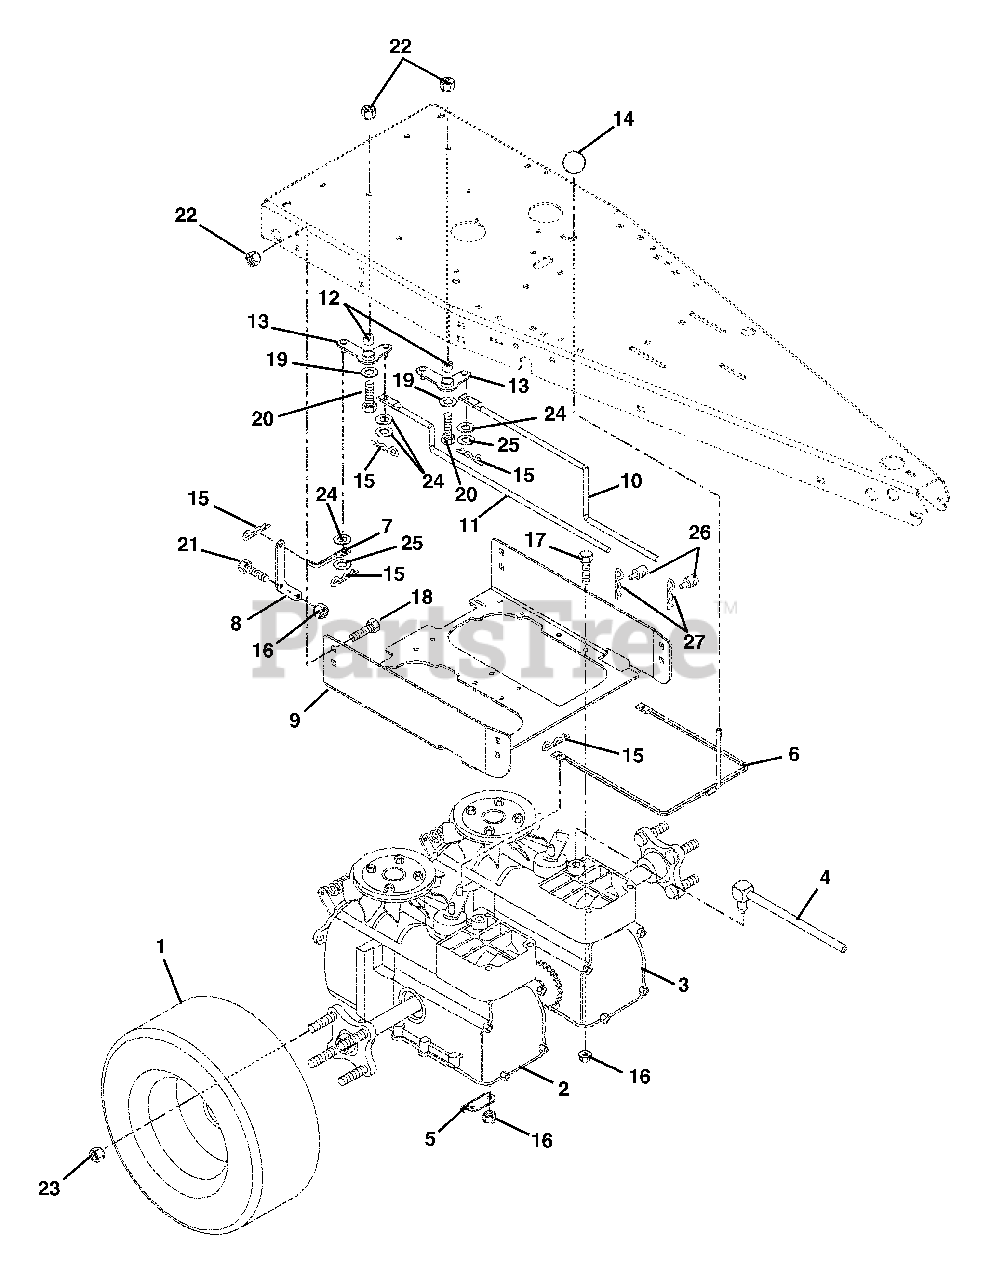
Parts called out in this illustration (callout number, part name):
1	T/WHL ASM 18X6.50-8 2 PLY
2	TRANSAXLE, HYDRO-GEAR
3	TRANSAXLE, HYDRO-GEAR
4	IZT, BREATHER ASSEMBLY
5	BRACKET-AXLE SUPPORT
6	DUMP ROD WLDM'T
7	ROD-BELL CRANK
8	BRACKET
9	CRADLE, IZT
10	ROD-STEERING LH
11	ROD-STEERING RH
12	BSHG-SLV .391X.688X.52 PM
13	WLDM'T-BELL CRANK
14	KNOB, BALL 5/16-18 X 1.5
15	PIN-HAIR, ENDRIES #25 YWZC
16	NUT-LK-TOP-FLG .31-18 BLKZC
17	@BLT-HEX .31-18X2.50 GR5 YWZC
18	BLT-RDHDSQNK .38-16X.75 G5BZ
19	@WSHR-FL-STL.38X.875X.083 YWZC
20	@BLT-HEX .38-16X1.25 GR5 YWZC
21	@BLT-HEX .31-18X.75 GR5 YWZC
22	NUT-LK-TOP-FLG .38-16 BLKZC
23	NUT-LUG .50-20 YWZC
24	WSHR-FL-STL .328X.87X.179 YWZC
25	WSHR-FL-STL .390X.75X.125 YWZC
26	TRUNNION, BRAKE .31-18 UNC
27	PIN-HAIR, ENDRIES #25 YWZC
